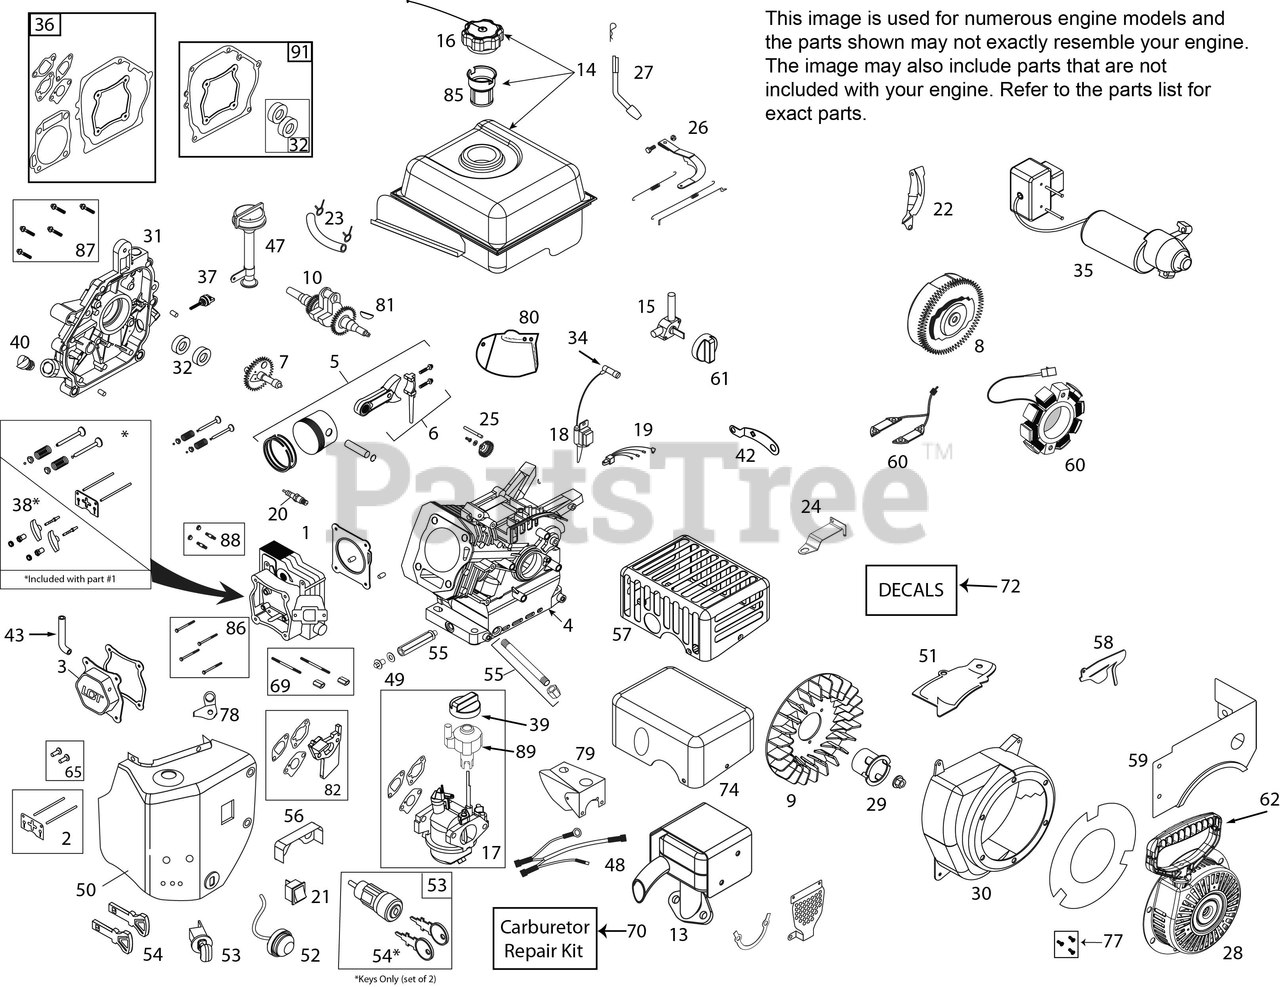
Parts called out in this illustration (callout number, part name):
1	CYLINDER HEAD ASSY (W/GASKET)
2	PUSH ROD & PLATE KIT (W/GASKT)
3	VALVE COVER (W/GASKET)
5	PISTON & ROD ASSEMBLY
7	CAMSHAFT - MCR
8	FLYWHEEL - MANUAL START
9	COOLING FAN - FLYWHEEL
10	CRANKSHAFT (#18 KEYED)
13	MUFFLER ASSEMBLY
14	FUEL TANK ASSEMBLY
14	MOUNTING BRACKET, FUEL TANK
15	PETCOCK W/KNOB AND TANK SKIRT
16	FUEL TANK CAP
17	CARBURETOR (W/GASKETS)
18	IGNITION COIL
20	SPARK PLUG, ARIENS AX
21	ON/OFF SWITCH - ROCKER
22	SHIELD - FLYWHEEL
23	FUEL HOSE KIT 1/4-230MMW/CLMPS
24	SPEED CONTROL BRACKET (FIXED)
25	GOVERNOR GEAR ASSEMBLY
26	GOVERNOR ARM & LNK KIT 3600RPM
27	GOVERNOR ARM PADDLE
28	RECOIL STARTER, 90 INCH ROPE
28	RECOIL ROLLER WELDMENT BRACKET
29	STARTER CUP RND STYLE STARTER
30	BLOWER HOUSING-BLACK W/BAFFLE
31	CRANKCASE COVER ASSEMBLY
32	OIL SEAL KIT(2 PCS 3/4" CRANK)
34	SPARK PLUG BOOT (W/MTL SHIELD)
36	ENGINE GASKET KIT
37	SMALL BLACK OIL DIPSTICK
38	ROCKER ARM KIT (W/GASKET)
39	CHOKE CONTROL KNOB
43	BREATHER TUBE
48	WIRE HARNESS
49	OIL DRAIN PLUG (W/WASHER)
50	HEATER BOX KIT
51	SHIELD - CYLINDER
52	PRIMER BULB WITH HOSE-SNOW (RED)
55	OIL DRAIN TUBE
57	MUFFLER SHIELD (CE)
58	GOVERNOR & CARBURETOR SHIELD
59	FUEL TANK SKIRT
61	PETCOCK W/KNOB AND SCREW
65	TAPPET KIT (SET OF 2)
69	CARBURETOR STUDS & COUPLNG KIT
70	CARBURETOR REPAIR KIT
72	LABEL KIT (2016) 208-254
74	MUFFLER HEAT SHIELD
77	RECOIL BOLT KIT
78	BREATHER TUBE BRACKET
81	WOODRUFF FLYWHEEL KEY 5-PACK
82	CARBURETOR SPACER KIT
85	FUEL TANK STRAINER
86	HEAD BLT KIT 136-179-208-254CC
87	CC COVER BLT KIT 179-208-254CC
88	MUFFLER MTG STUD KIT
91	CRANKCASE GASKET KIT 208GEN1&2
9999	HIGH ALT JET-208CC L10-1 CARB
9999	HARDWARE KIT (4 M6X10 FLG BLT)
